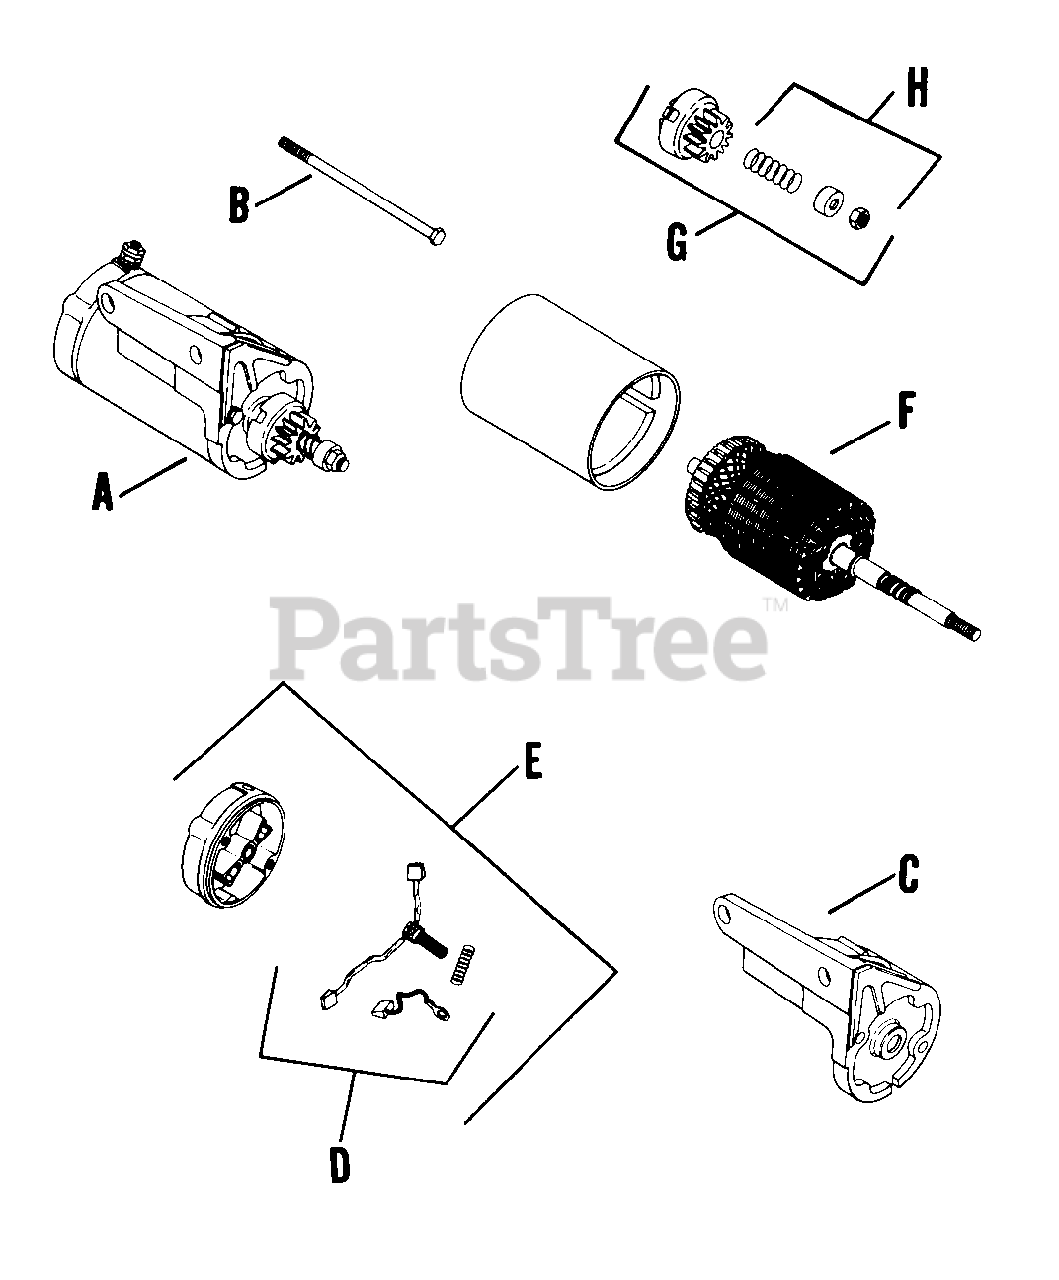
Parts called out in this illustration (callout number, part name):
A	STARTER - USE A-237511
B	SCREW - USE 12 086 02
C	BRACKET - DISCONTINUED
D	KIT - USE 52 755 15
E	CAP - DISCONTINUED
